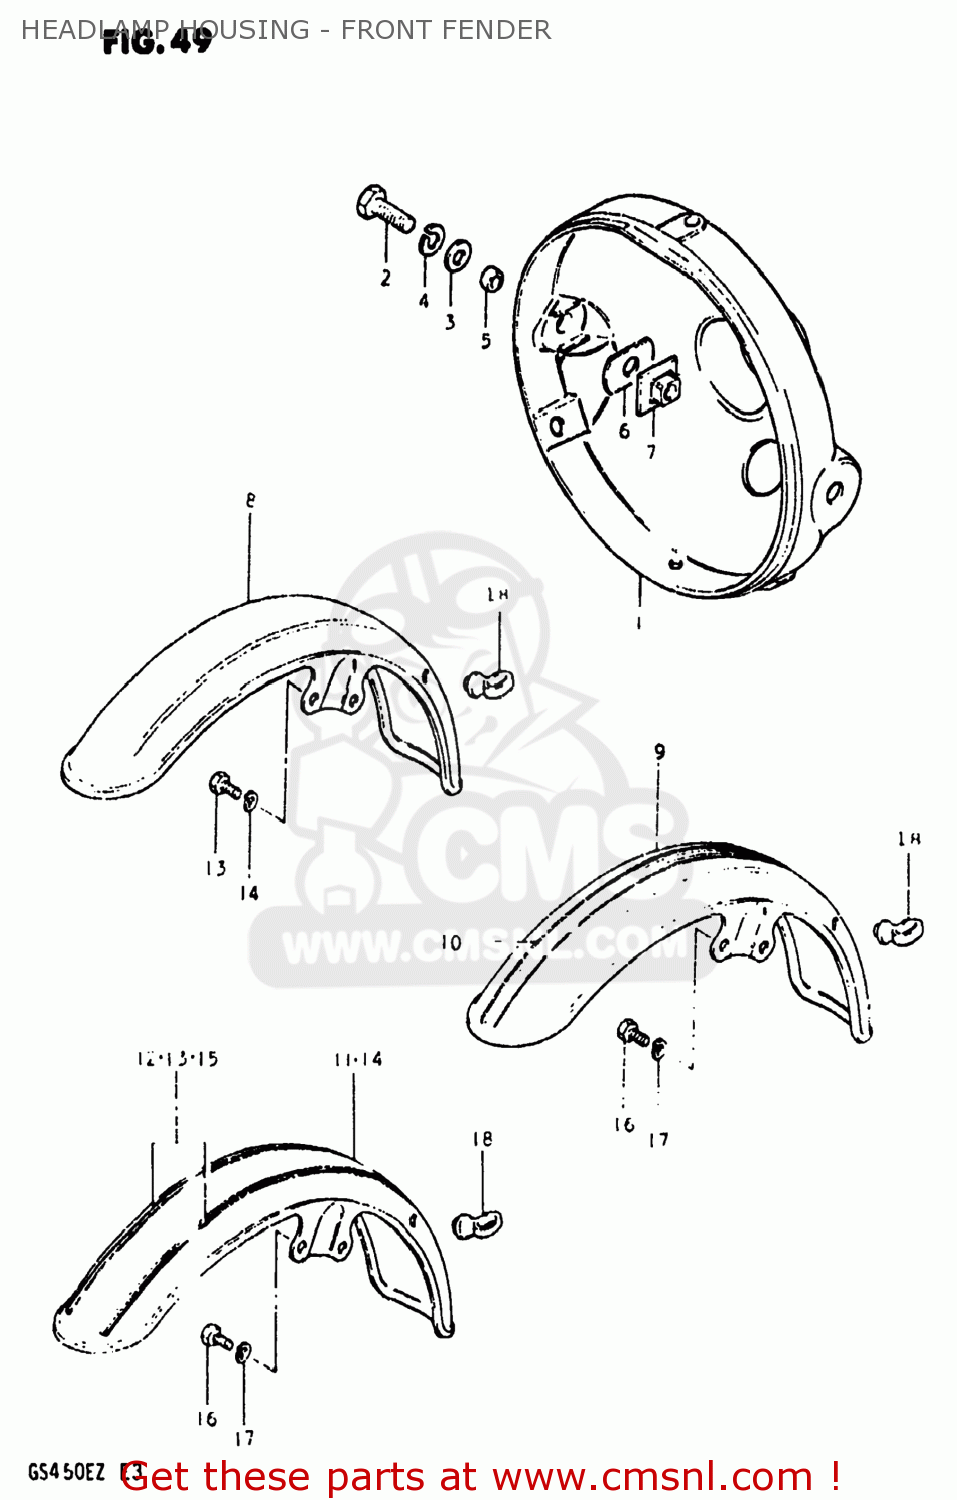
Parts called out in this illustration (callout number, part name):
1	HOUSING,HEADLAMP
2	BOLT
3	WASHER
4	LOCK WASHER
5	SPACER (8.8X12X7)
6	CUSHION
7	PLATE,HEADLAMP HOUSING
8	FENDER,FRONT
9	FENDER,FRONT
10	TAPE,FRONT FENDER
11	FENDER,FRONT
12	TAPE,FRONT FENDER
13	TAPE,FRONT FENDER
14	FENDER,FRONT
15	TAPE,FRONT FENDER
16	BOLT
17	LOCK WASHER
18	GUIDE,CABLE
